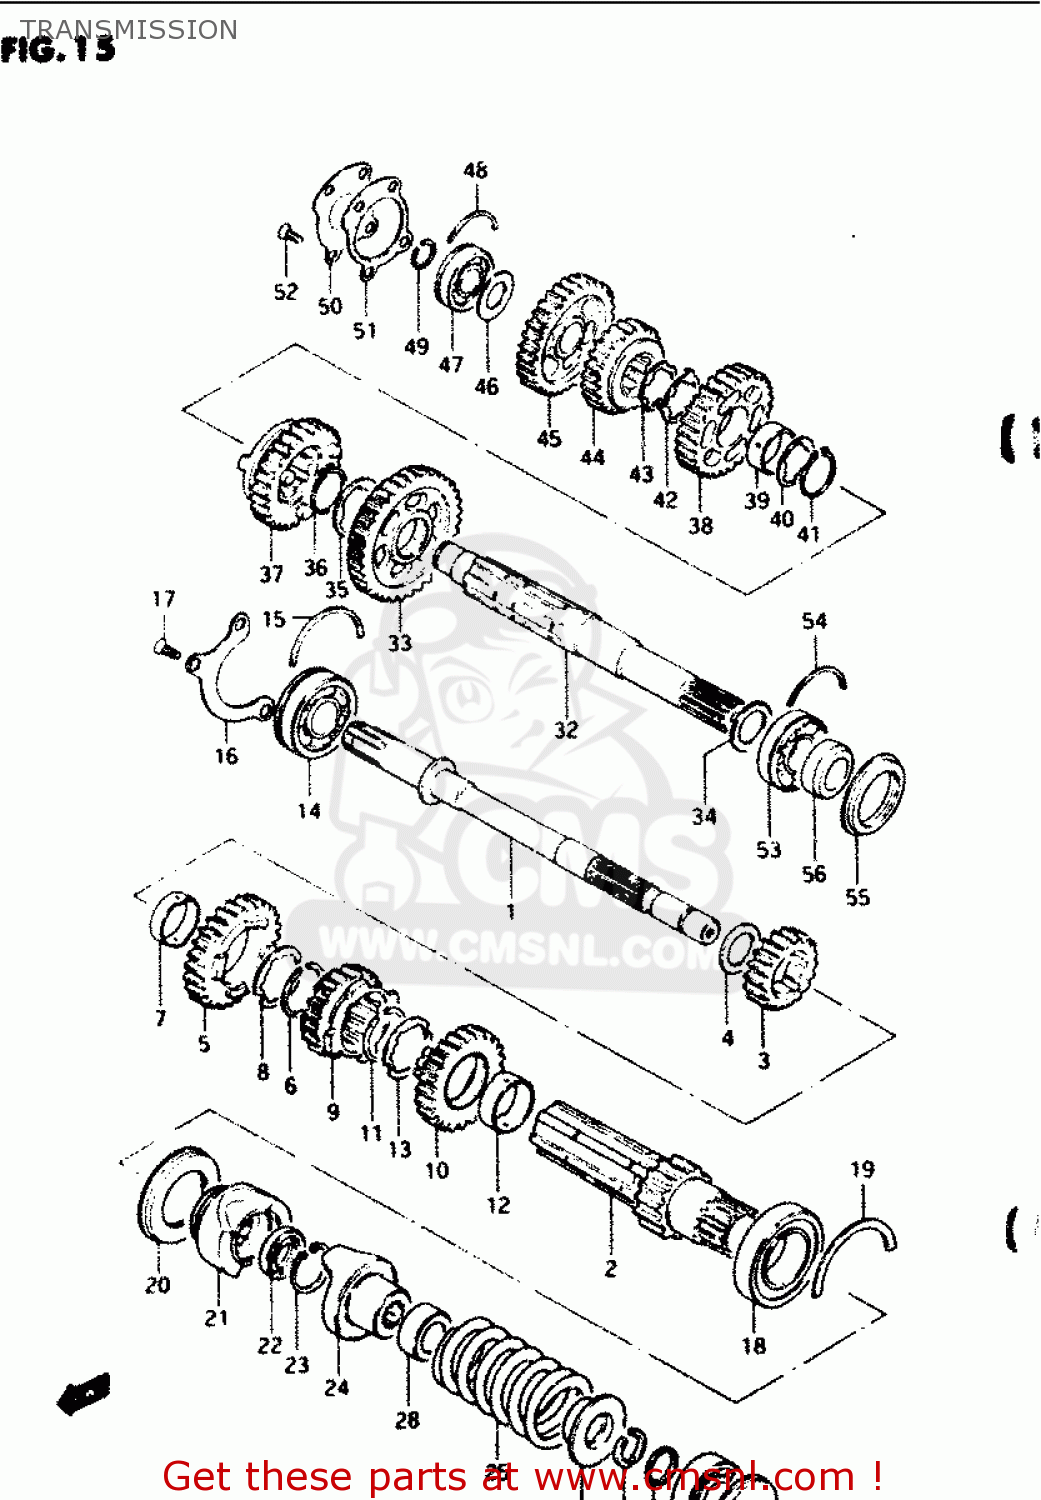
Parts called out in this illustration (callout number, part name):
1	SHAFT,INNER COUNTER
2	SHAFT,OUTER COUNTER
3	GEAR,SECOND DRIVE
4	WASHER (21X35X2)
5	GEAR,5TH DRIVE(NT:26)
6	RING,SNAP
7	SPACER,DRIVE GEAR
8	LOCK WASHER,5TH DR GEAR SPACER
9	GEAR,THIRD DRIVE
10	GEAR,FOURTH DRIVE
11	RING,SNAP
12	SPACER,DRIVE GEAR
13	LOCK WASHER,5TH DR GEAR SPACER
14	BEARING(25X62X17)
15	C-RING
16	RETAINER,CNTR SHAFT BEARING
17	SCREW
18	BALL BEARING 32X58X13
19	C-RING
20	SEAL,OIL(40X58X7)
21	DOG,OUTPUT CAM
22	SEAL,OIL(20.6X31X6)
23	CIRCLIP
24	DOG,INPUT CAM
25	SPRING
26	STOPPER,CAM DOG SLIDING
27	STOPPER,CAM DOG
28	GUIDE,CAM DOG SPRING
29	BEARING(17X40X12)
30	SPACER (17X21X3.5)
31	PLUG
32	SHAFT,DRIVE
33	GEAR,FIRST DRIVEN
34	WASHER, LH
35	WASHER,LOCK
36	CIRCLIP
37	GEAR,FOURTH DRIVEN
38	GEAR,THIRD DRIVEN
39	BUSH,3RD DRIVEN GEAR
40	WASHER,LOCK
41	CIRCLIP
42	WASHER
43	WASHER,LOCK
44	GEAR,FIFTH DRIVEN
45	GEAR,SECOND DRIVEN
46	WASHER
47	BEARING(20X47X14)
48	C RING
49	CIRCLIP
50	PLATE,DRIVESHAFT
51	GASKET,DRIVESHAFT PLATE (MCA)
52	SCREW
53	BEARING
54	C RING
55	SEAL,OIL(35X52X6)
56	SPACER,DRIVESHAFT,LEFT
